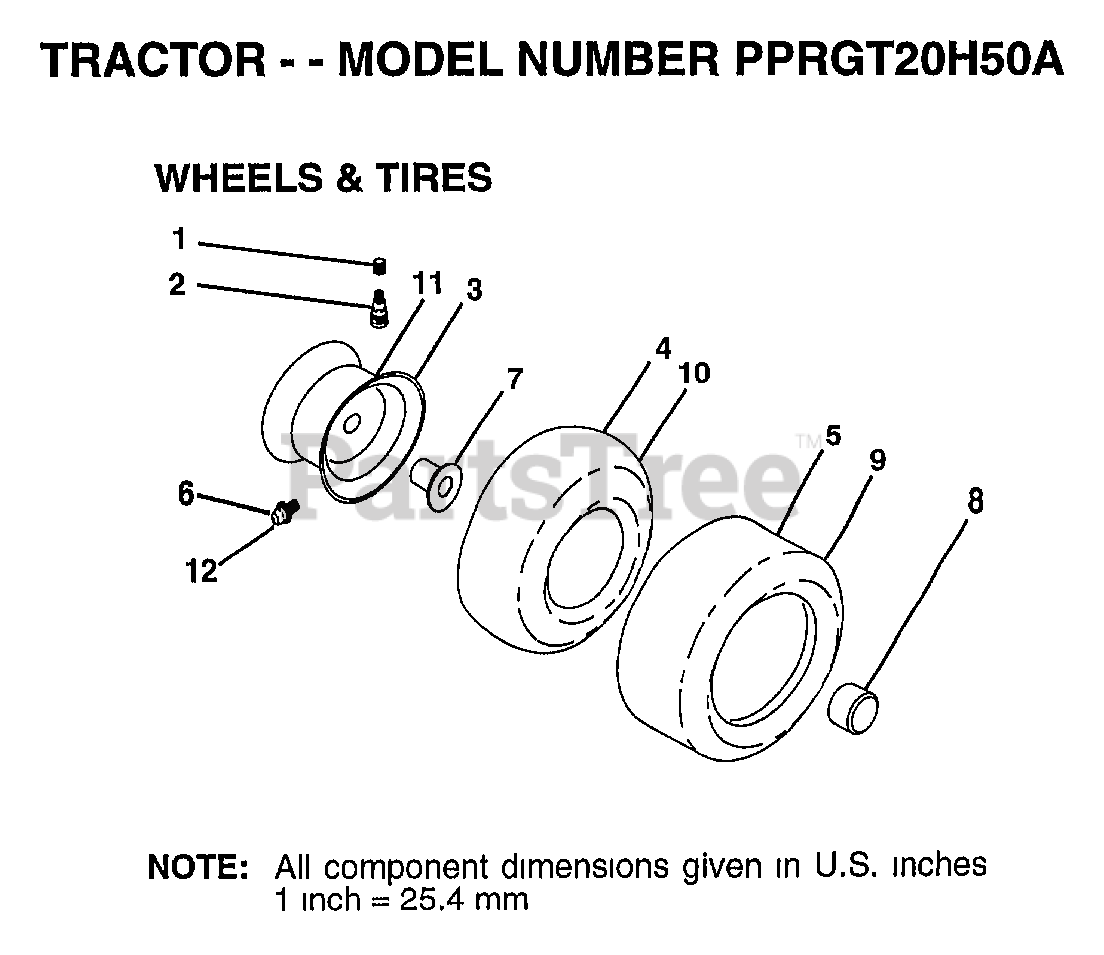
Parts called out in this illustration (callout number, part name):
1	VALVE CAP
2	VALVE STEM LT
3	"RIM ASM 8"" FRT"
4	TUBE.16X6.5/7.5-8
6	FITTING LT
7	"FLANGE, BEARING"
8	HUB CAP
10	TUBE.23X8/10-12
11	"RIM ASM 12"" REAR"
12	ZERK FITTING M
